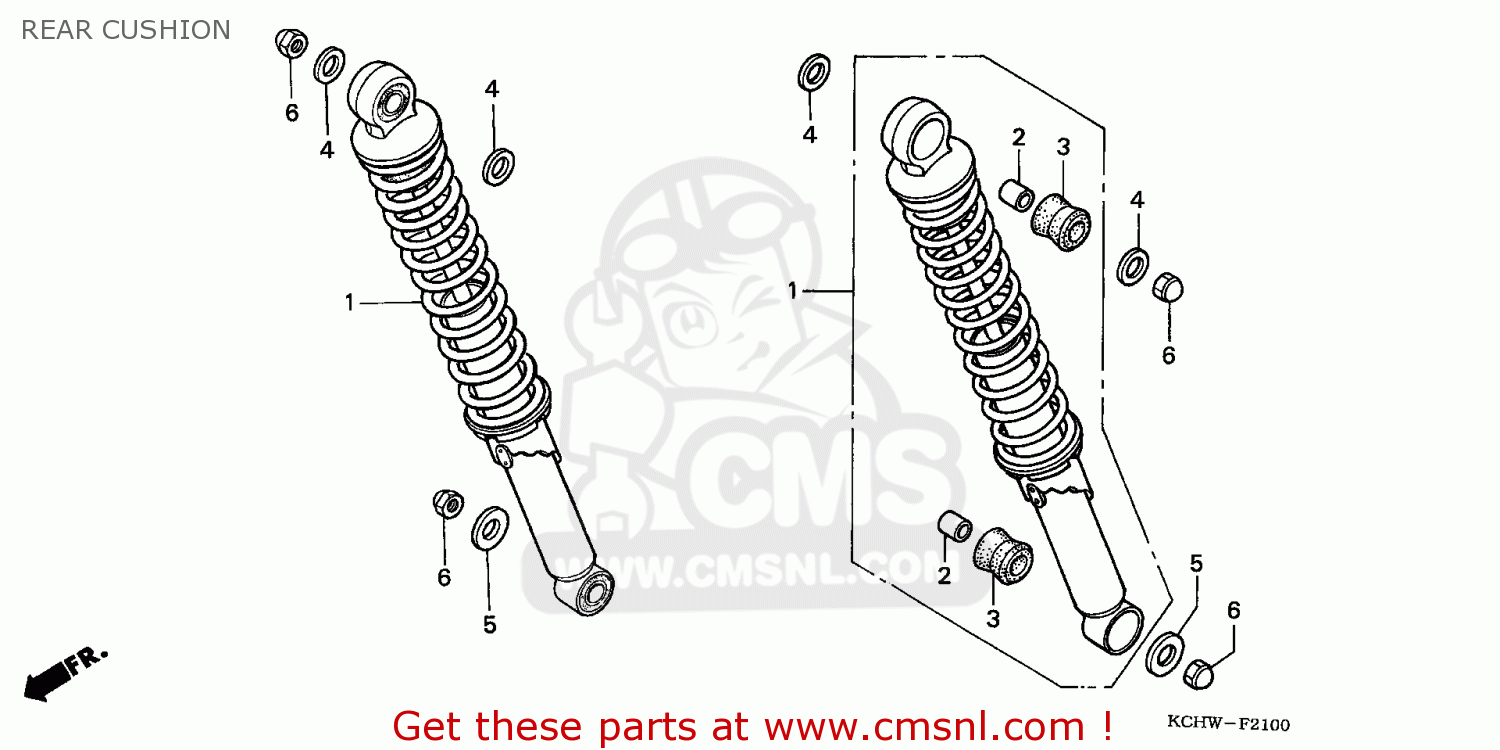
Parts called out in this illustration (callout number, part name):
1	CUSHION ASSY,REAR
2	COLLAR, CUSHION
3	BUSH,RUBBER
4	WASHER,PLAIN,12MM
5	WASHER,10.3MM
6	NUT, 10MM
